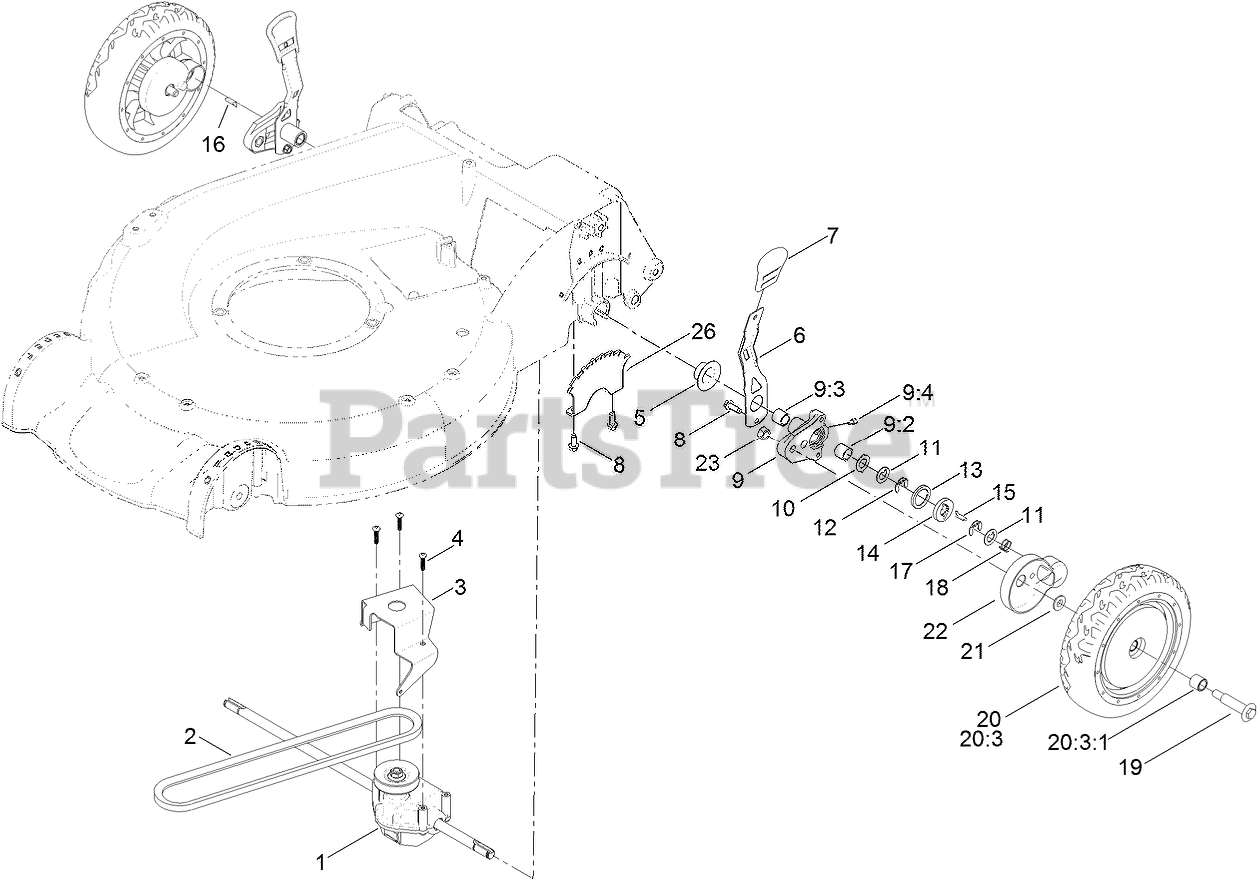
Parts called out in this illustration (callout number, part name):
1	TRANSMISSION ASM
2	V-BELT
3	BRACKET-TRANSMISSION
4	SCREW-PLASTITE
5	CAP-END
6	ARM-SPRING
7	KNOB-HOC
8	SCREW-HWHTF
9	PIVOT ARM ASM
9:2	BUSHING
9:3	BUSHING
9:4	FITTING-GREASE
10	WASHER-ARM, PIVOT
11	WASHER-THRUST, KEYED
12	RING-CLIP, LOCKING
13	RING-FRICTION
14	WASHER-CLUTCH
15	KEY-ROCKING, LH
16	KEY-ROCKING, RH
17	GEAR-PINION
18	SPRING-COMPRESSION
19	BOLT-SHOULDER
20	WHEEL GEAR ASM
20:3	WHEEL ASM
20:3:1	BUSHING
21	SPACER-COVER, WHEEL
22	COVER-WHEEL
23	NUT-HEX
26	PLATE-HOC
